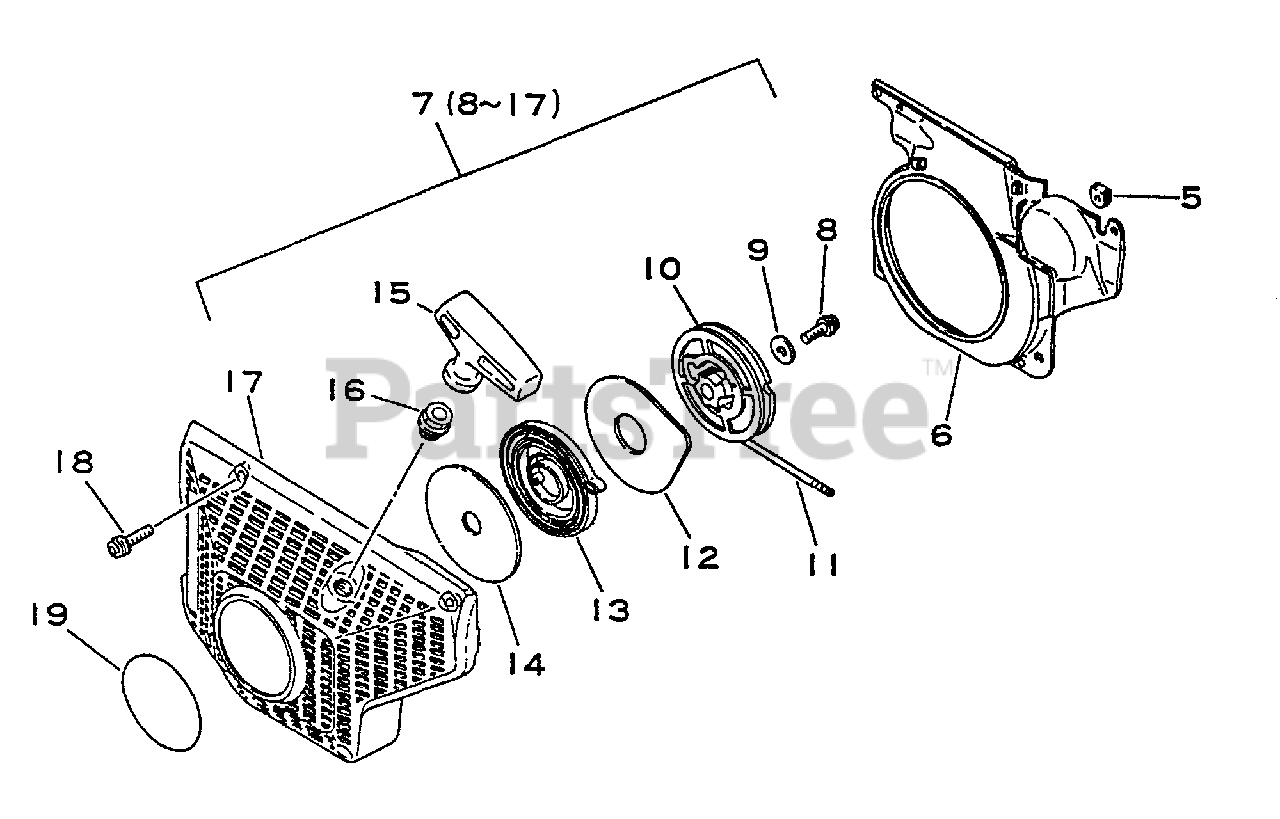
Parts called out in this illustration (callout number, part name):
6	SHIELD, FAN
7	STARTER ASSY
8	SCREW 5×14
9	WASHER 5.5×12×0.8
10	REEL, ROPE
11	ROPE, STARTER
12	PLATE, SIDE
13	SPRING, RECOIL
14	PLATE, SIDE
15	GRIP, STARTER
16	GUIDE, ROPE
17	CASE, STARTER
18	SCREW 5×20
19	LABEL - ECHO
